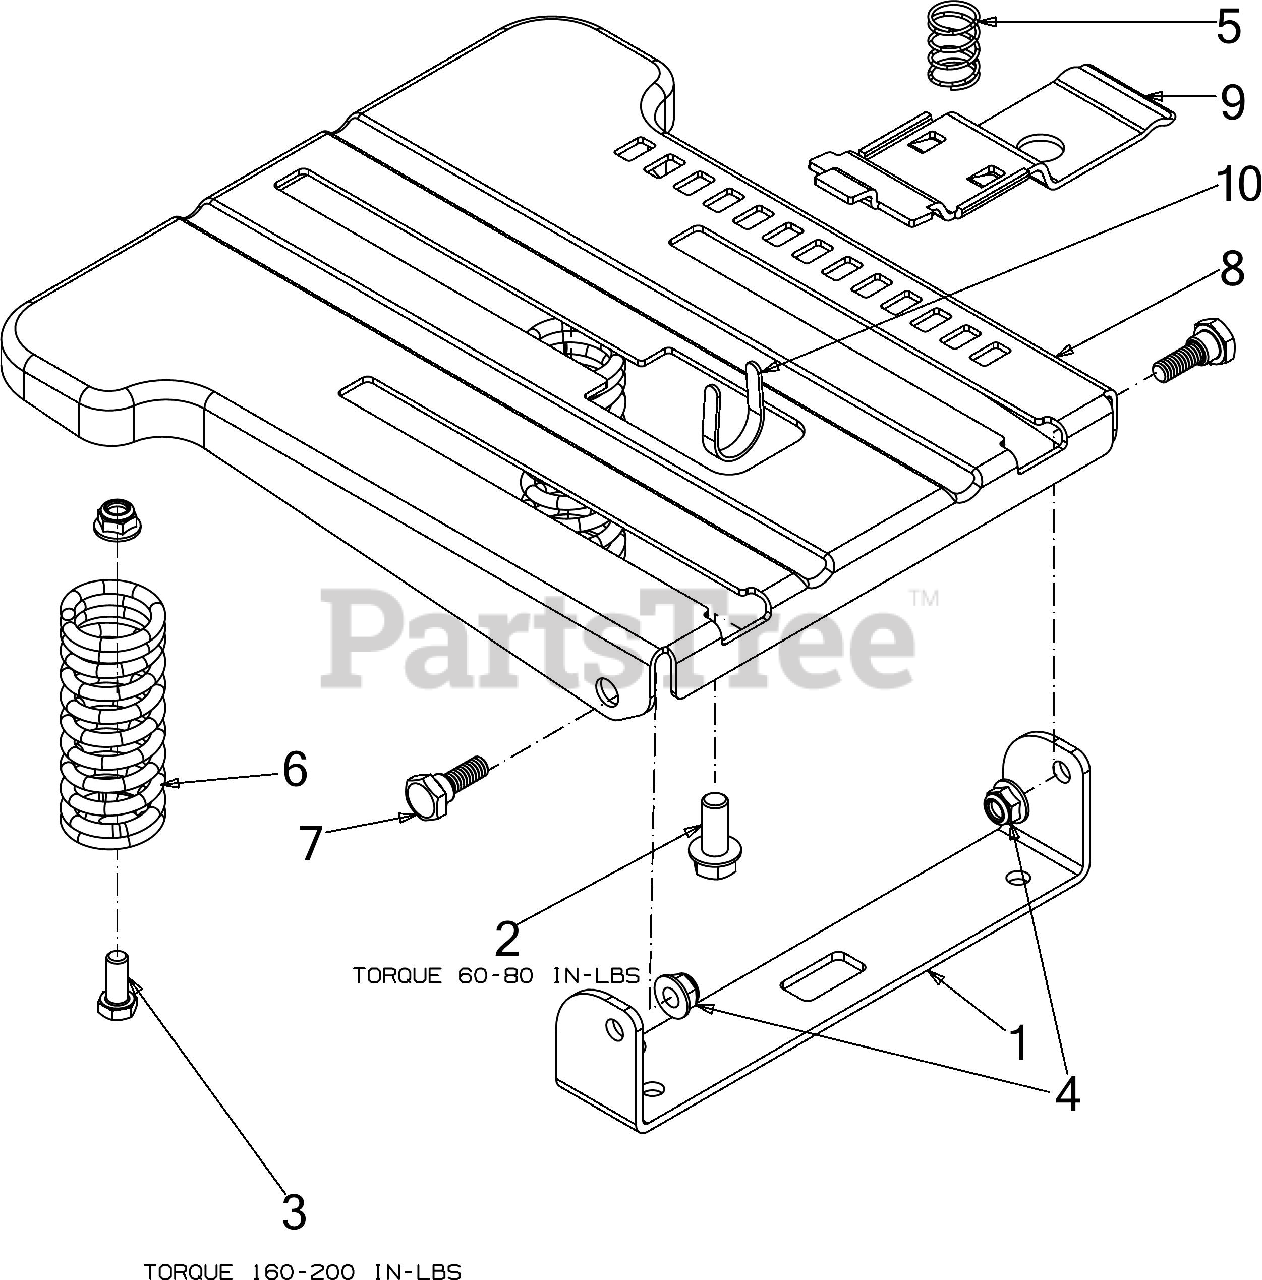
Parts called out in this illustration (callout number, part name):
1	SEAT PIVOT BRACKET
2	SCREW 3/8-16 x .875 GR5
3	SCREW 5/16-18 x .75 GR5
4	FLANGE LOCK NUT 5/16-18
5	COMPRESSION SPRING
6	COMPRESSION SPRING
7	SHOULDER SCREW .437
8	SEAT MOUNTING BRACKET
9	SEAT ADJUST LEVER
10	RETAINING CLIP
